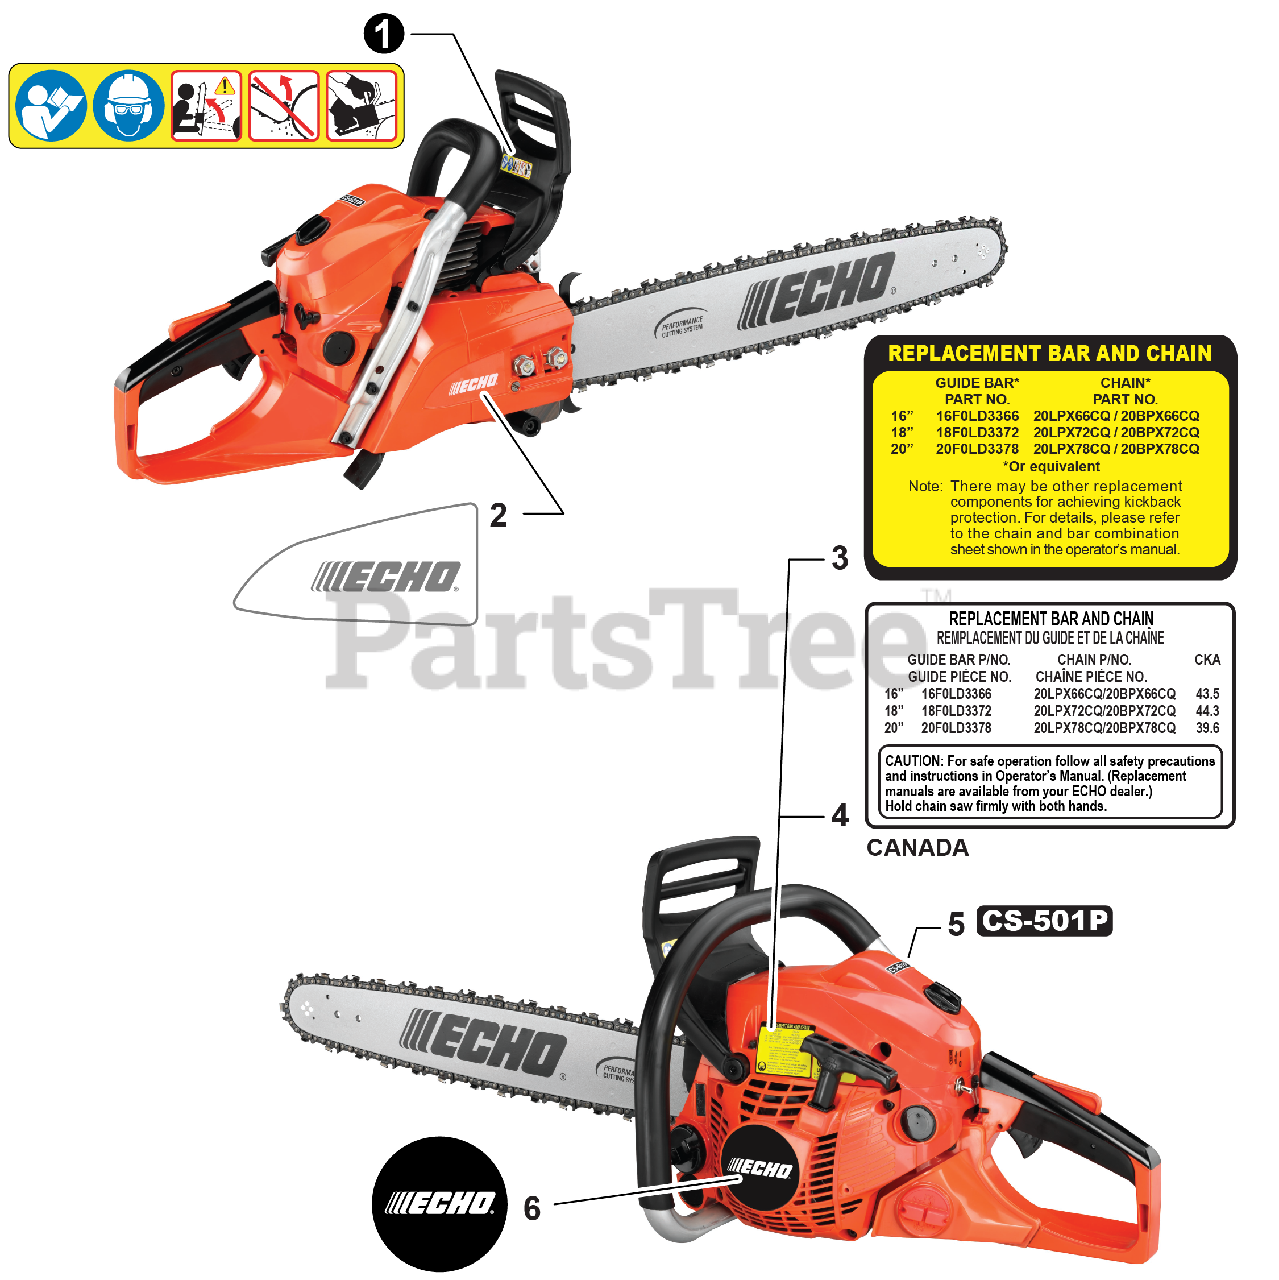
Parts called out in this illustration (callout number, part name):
1	LABEL, CAUTION
2	LABEL, ECHO
3	LABEL, BAR & CHAIN
4	LABEL, BAR & CHAIN
5	LABEL, CS-501P
6	LABEL, RECOIL STARTER
